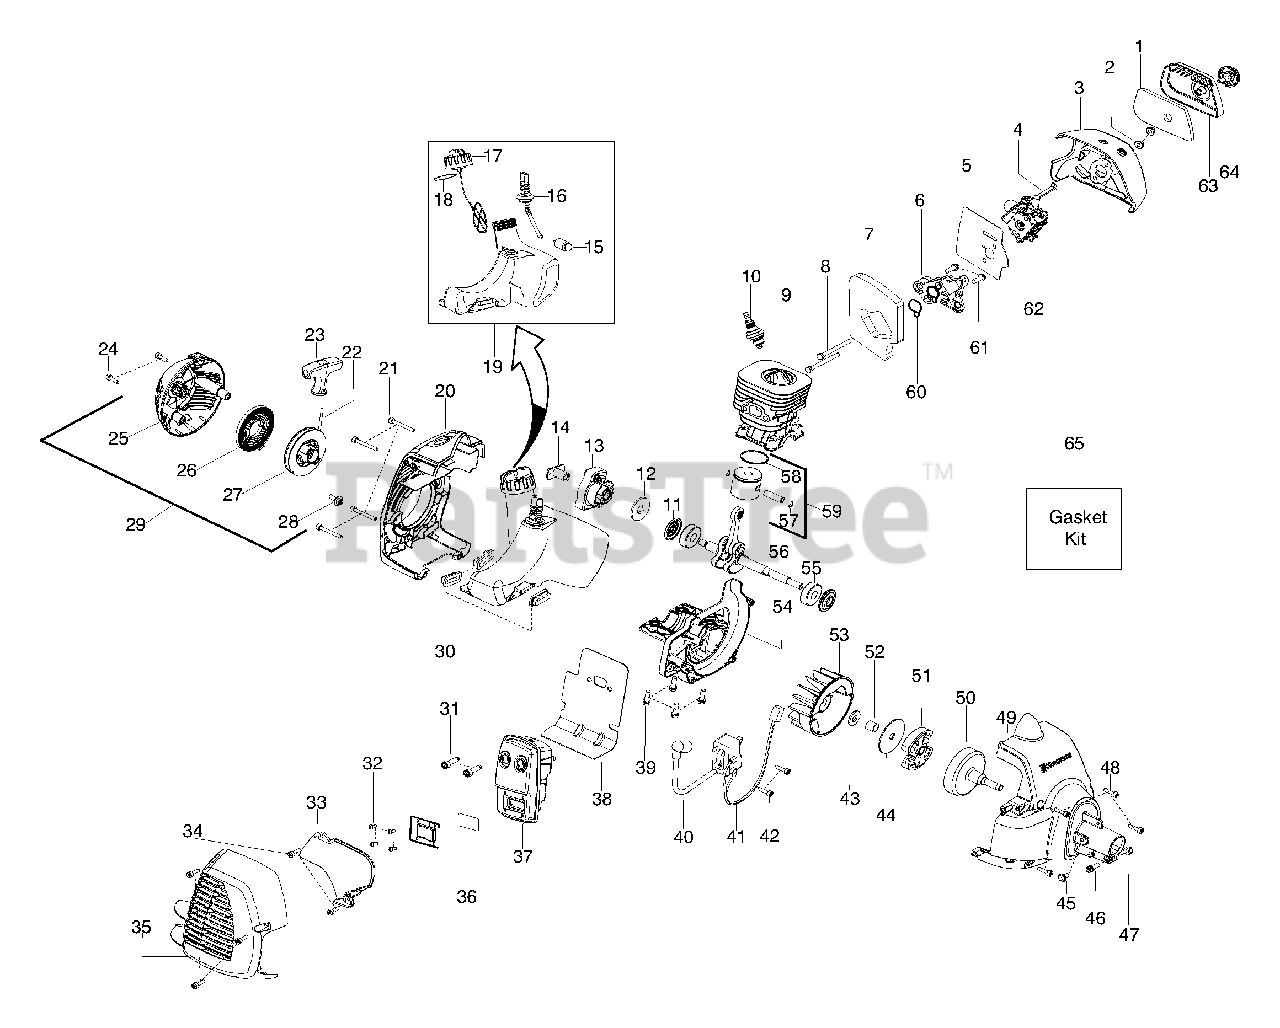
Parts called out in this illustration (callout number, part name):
2	Nut-Carb. Screw
3	Air Box
4	Lever - Choke
5	Kit-Carb. Gasket
6	Adaptor-Carb.
7	Kit-Gasket (foam)
9	Cylinder
10	Plug-Spark
11	Kit-Crankshaft seal
12	Washer-Flat
13	Assy-Starter Cup
14	Coupling-Starter
15	Assy-Fuel Filter
16	Kit-Fuel Line
17	Assy-Cap w/ret.
18	O-ring - Fuel Cap
19	Assy-Fuel Tank
20	Shroud-Rear
23	Handle-Starter
25	Starter Hsg. w/eyelet
26	Kit-Starter Spring
27	Kit-Starter Pulley
29	Assy-Starter Hsg.
30	Isolator-Tank
31	Bolt-Muffler
33	Shield-Heat
35	Guard-Muffler
36	Kit-Spark Arrestor
37	Assy-Muffler
38	Gasket-Paper Metal
40	Module
41	Assy-Leadwire
44	Washer-Clutch
49	Assy-Fan Housing
50	Assy-Clutch Drum
51	Kit-Clutch Assy.
56	Kit-Crankshaft
57	Retainer-Piston Pin
58	Ring-Piston
59	Kit-Piston
60	Kit-Gasket
62	Kit-Carb.
63	Cover-Air Box
65	Kit-Gasket
